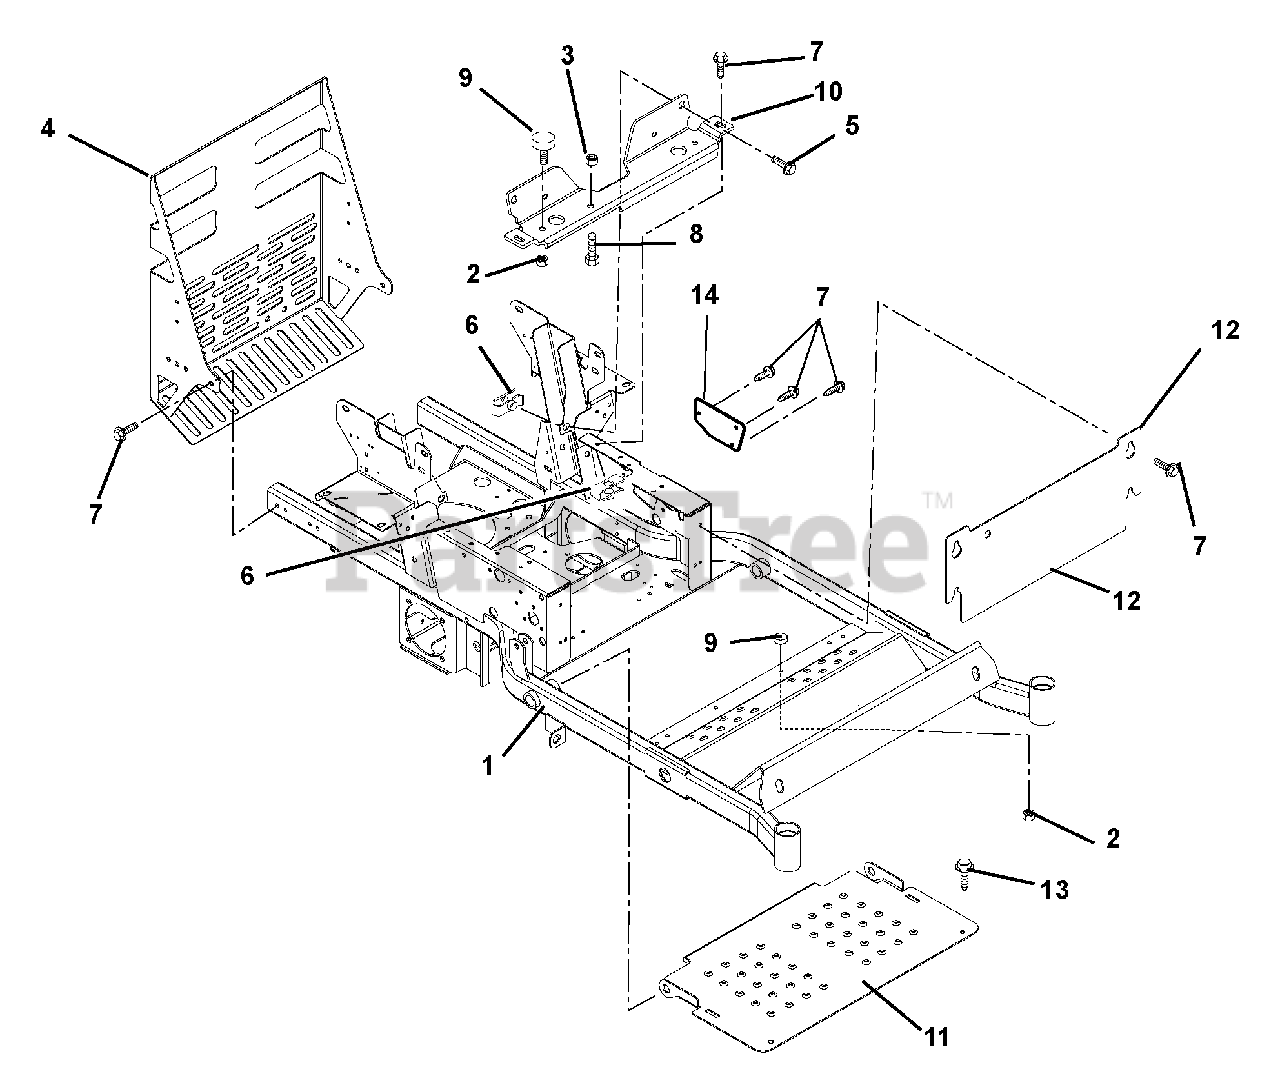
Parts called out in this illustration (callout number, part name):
1	Intermediate Z Frame
2	Nut, Spin Lock Flange .312-18
3	Nut, Locking Top Flange .31-18
4	Bumper with Heat Shield
5	Bolt, Serrated Flange Washer Head .38-16 x 1.00
6	Nut, Retainer .375-16 x .37
7	Screw, Tapping Hex Washer Head .38-16 x .50
8	Bolt, Hex .31-18 x 1.25 Grade 5
9	Bumper, Rubber
10	Seat Support
11	Footrest Panel
12	Access Panel
13	Screw, Tapping .38-16 x 1.00 Hex Washer Head
14	Valve Cover
